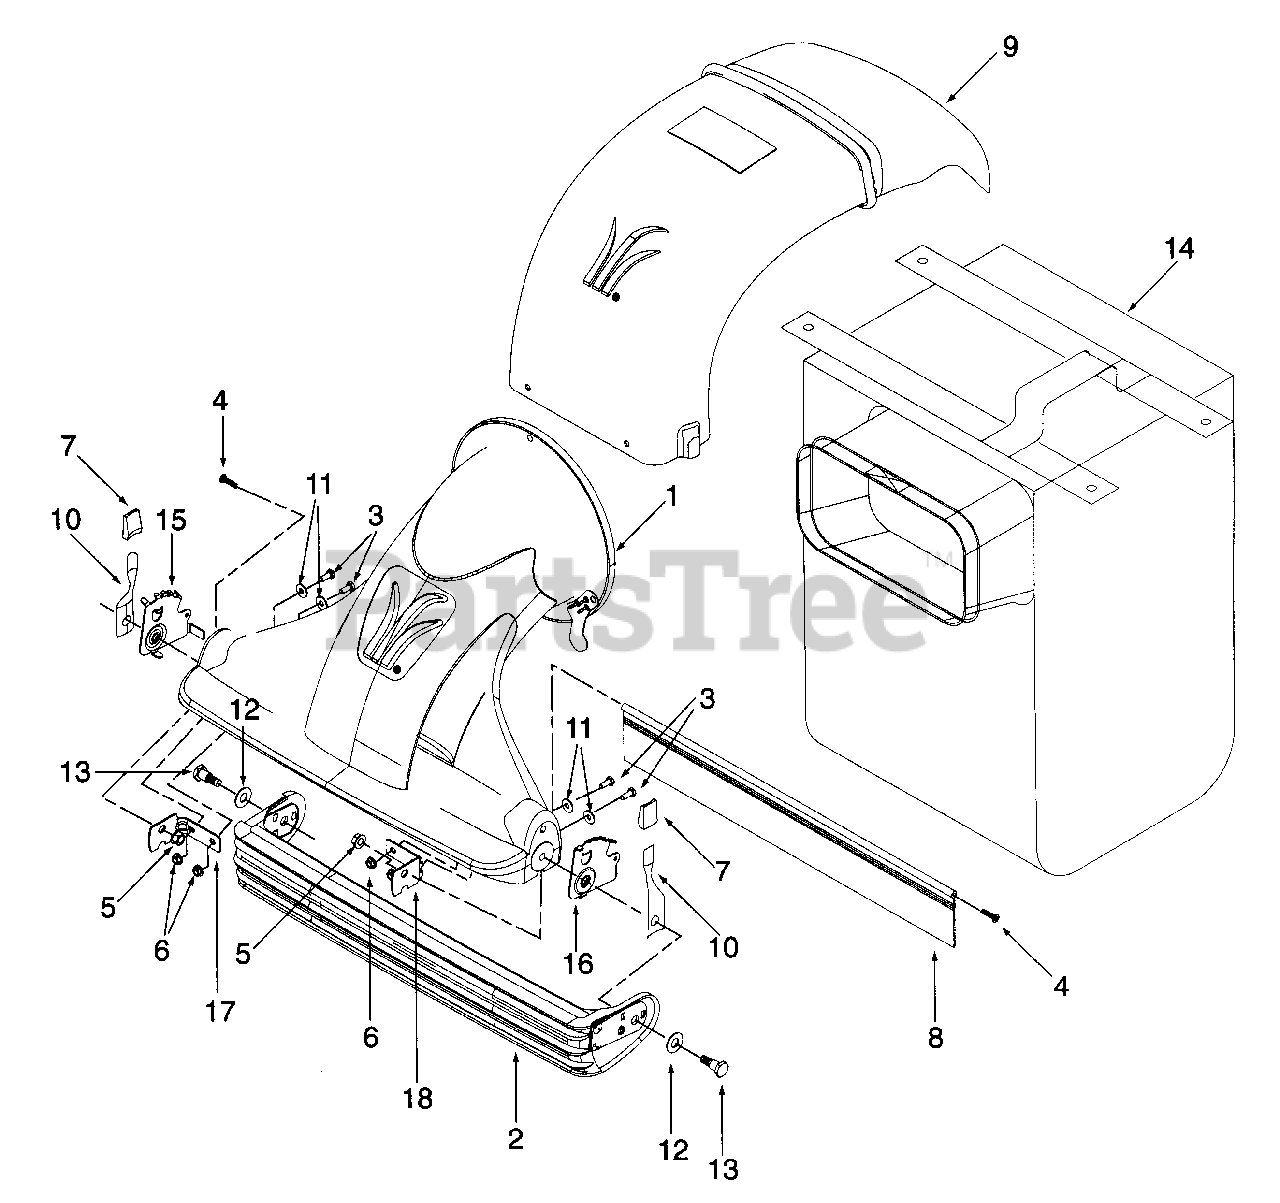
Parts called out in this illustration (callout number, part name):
1	NOZZLE ASSEMBLY
2	DOOR ASSEMBLY
3	HEX CAP SCREW 1/4-20 x .625
4	PHILLIPS TRUSS SCREW-HI-LO #12 x 1.00
5	FLANGED LOCK NUT 3/8-16
6	HEX FLANGED LOCK NUT 1/4-20
7	HEIGHT ADJUSTMENT KNOB
8	NOZZLE FLAP
9	DISCHARGE CHUTE
10	SPRING LEVER
11	FLAT WASHER .28 - .74 id. .063 od.
12	FLAT WASHER .510 - 1.120 x .060
13	SHOULDER SCREW .5 x .545 x 3/8-16
14	3 BUSHEL BAG
